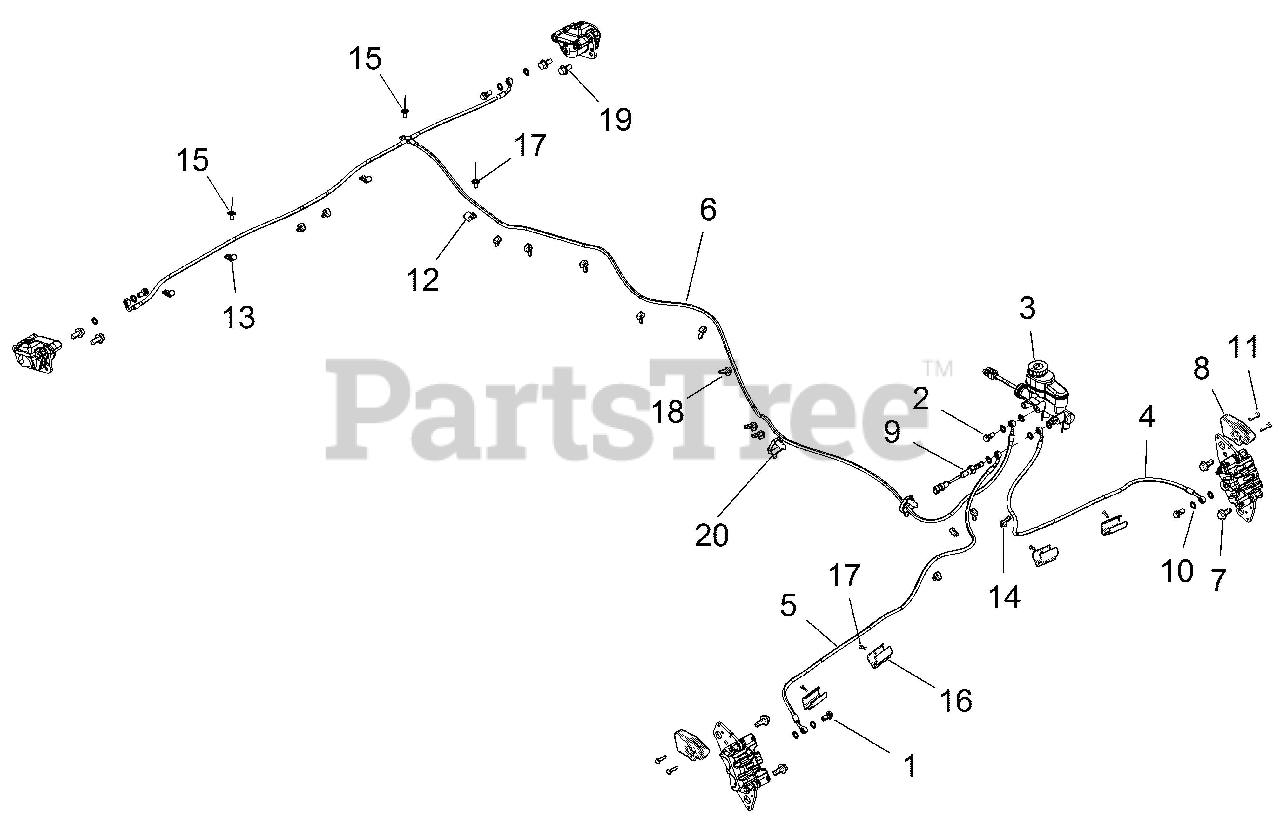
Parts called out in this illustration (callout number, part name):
1	BOLT-BANJO,10MMX1.00
2	BOLT-BANJO, 10MM X 1.25-6G
3	ASM-MASTER CYLINDER,UV,GS
4	LINE-BRAKE,FRONT,LEFT,BRD
5	LINE-BRAKE,FRONT,RIGHT,BRD
6	LINE-BRK,3WAY,123",20B,90B,90B
7	BOLT-M10X1.25X25,HXFLG,W/PATCH
8	SCRAPER-BRAKE,FRONT
10	SEAL-STAT-O-3/8,70EP
12	CLAMP, CABLE
13	CLAMP,HOSE
14	CLIP-ROUTING
15	RIVET(50) *
16	RETAINER-BRAKE LINE,1"
17	POP RIVET(50)
19	BOLT-M10X1.25X20,HXFLG-OLV D
20	CLIP-ROUTING
